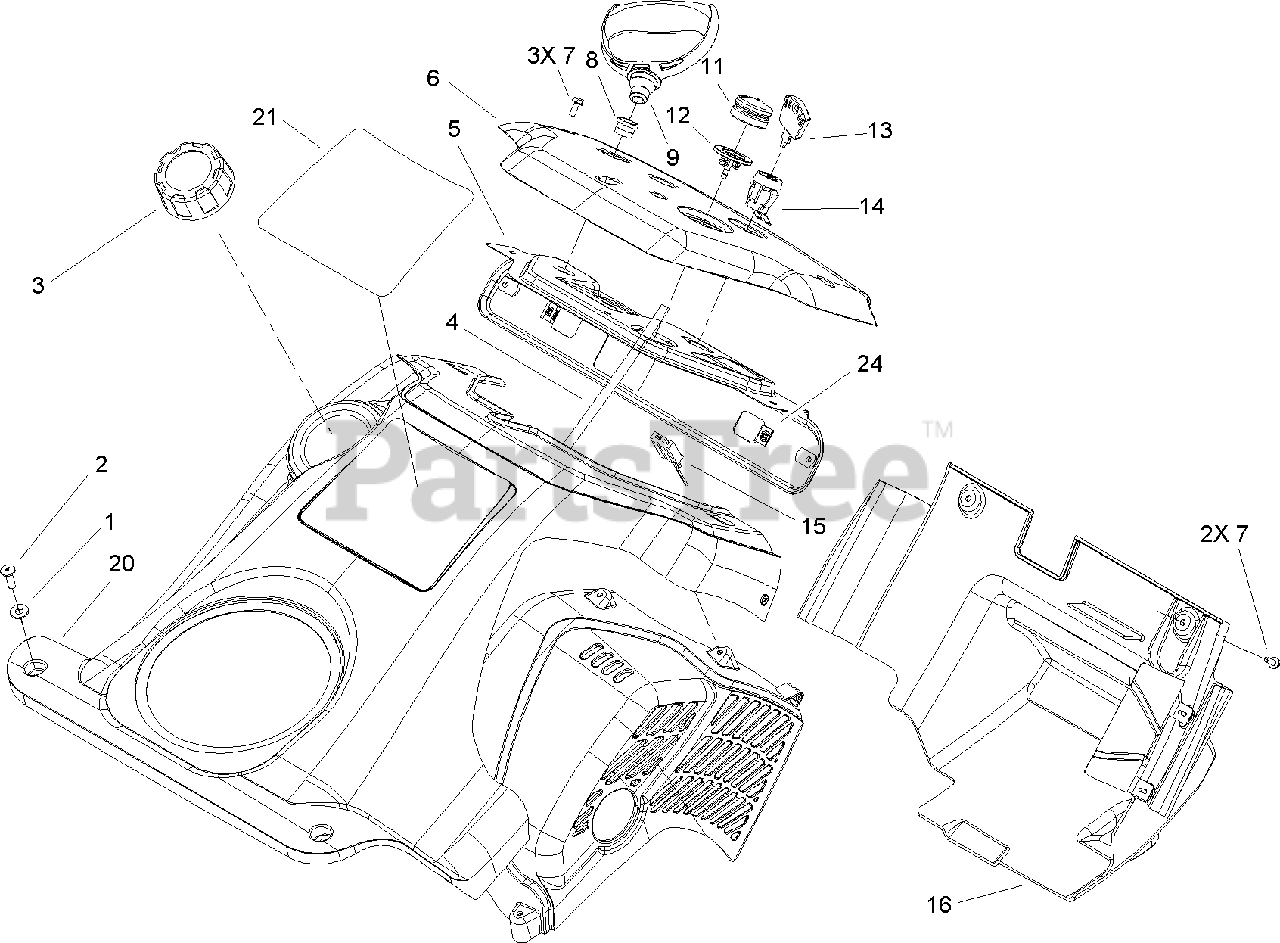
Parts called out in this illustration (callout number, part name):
1	WASHER-FLAT
2	SCREW-PPH
3	GAS CAP ASM
4	HOSE-PRIMER
5	PANEL-SUPPORT, CONTROL
6	PANEL-CONTROL
7	SCREW-HWH
8	GUIDE-ROPE, STARTER
9	HANDLE-RECOIL
11	BULB-PRIMER
12	BODY-PRIMER
15	CONNECTOR-BODY
16	LOWER SHROUD / BAFFLE ASM
20	UPPER SHROUD ASM
21	DECAL-UPPER SHROUD
24	NUT-SPEED, U-TYPE
